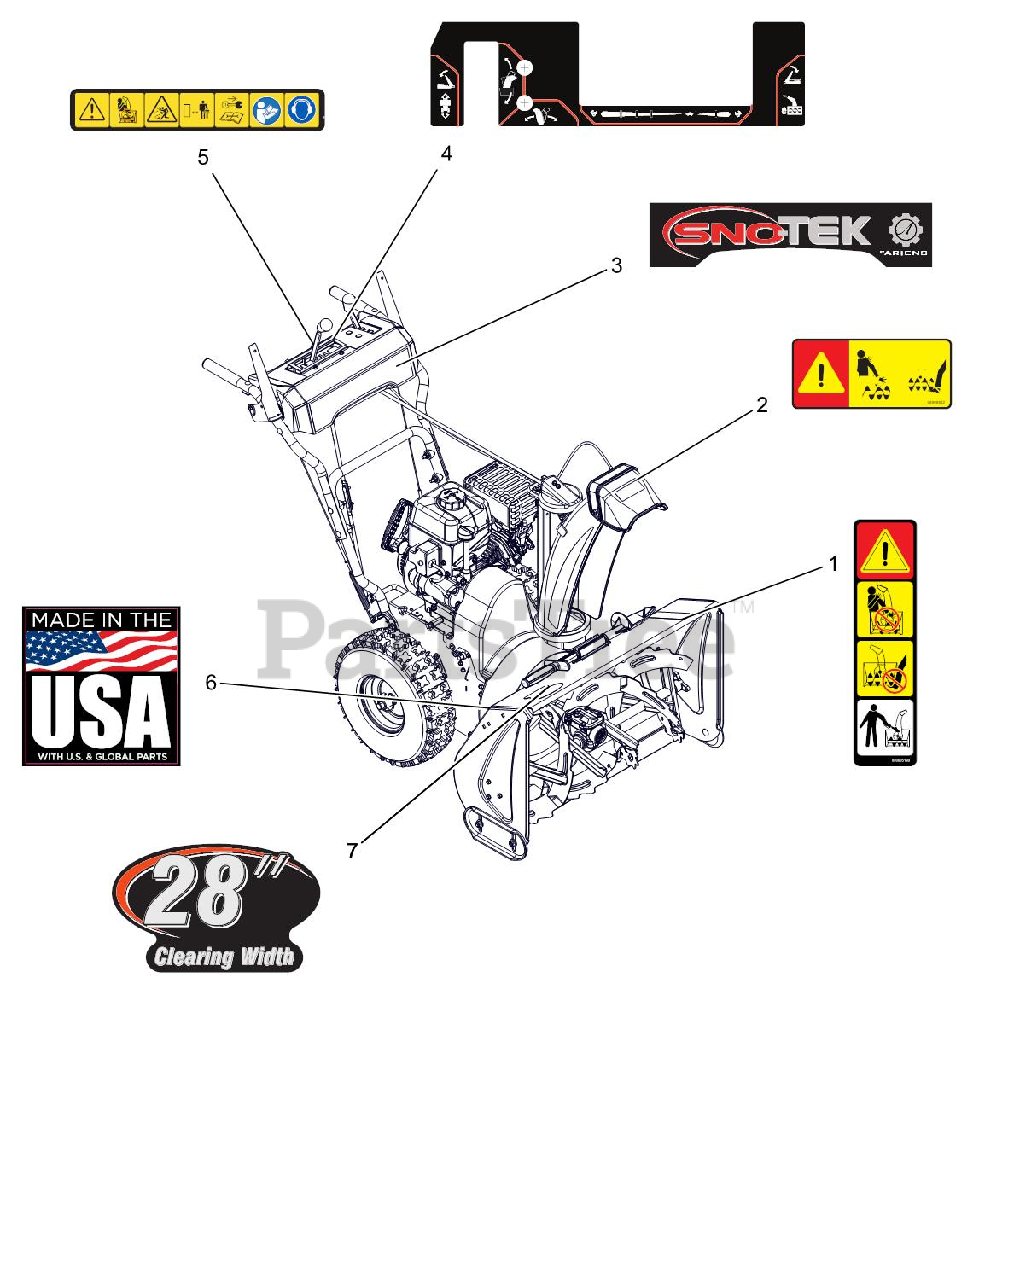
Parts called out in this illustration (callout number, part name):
1	DECAL, DANGER - ROTATING PARTS
2	DECAL, DANGER SNO-TEK
3	DECAL, DASH, SNO-TEK
4	DECAL,CONTROL-COMP REMOTE
5	DECAL,DASH - SAFETY
6	DECAL, MADE IN USA
7	DECAL, HOUSING SNO-TEK 28
